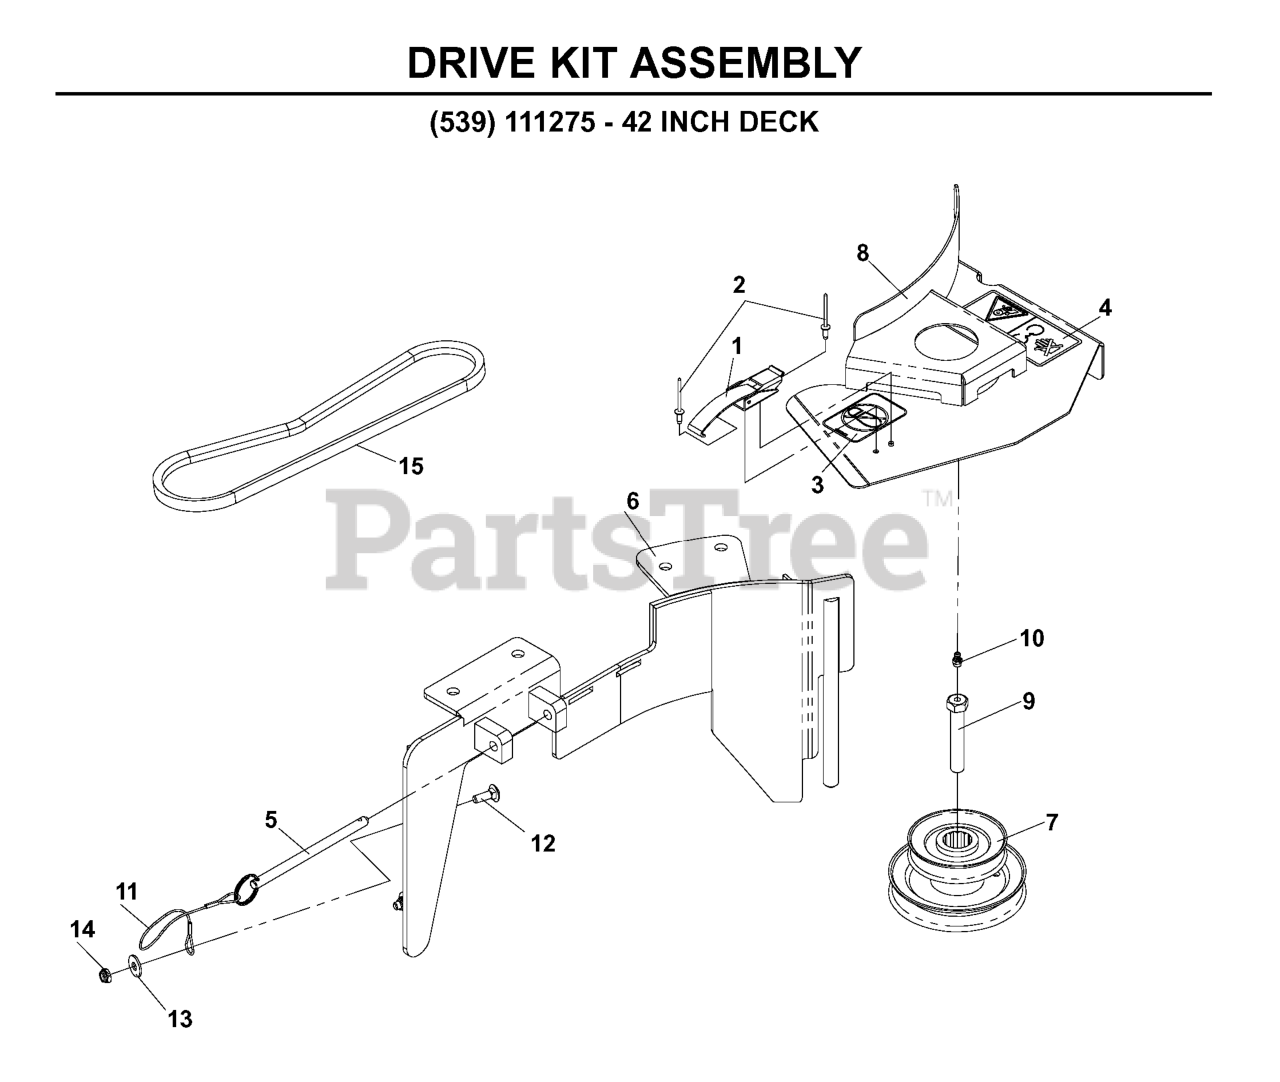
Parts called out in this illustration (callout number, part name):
1	DRAW LATCH
2	RIVET, BLIND, 5/32 DIA
3	DECAL, NO STEP
4	DECAL, BELT DRIVE
6	BLOWER DECK PLATE
7	42/48 LG DBL HEX STACK PULLEY
8	BELT SHIELD ASSY, 42"
9	DRILLED BOLT 7/16-20 X 2 1/2"
10	ZERK
12	RHSNB 1/4C X 3/4
13	WASHER 1/4 FLAT
14	JAM NUT 1/4C (2 2 PW01)
